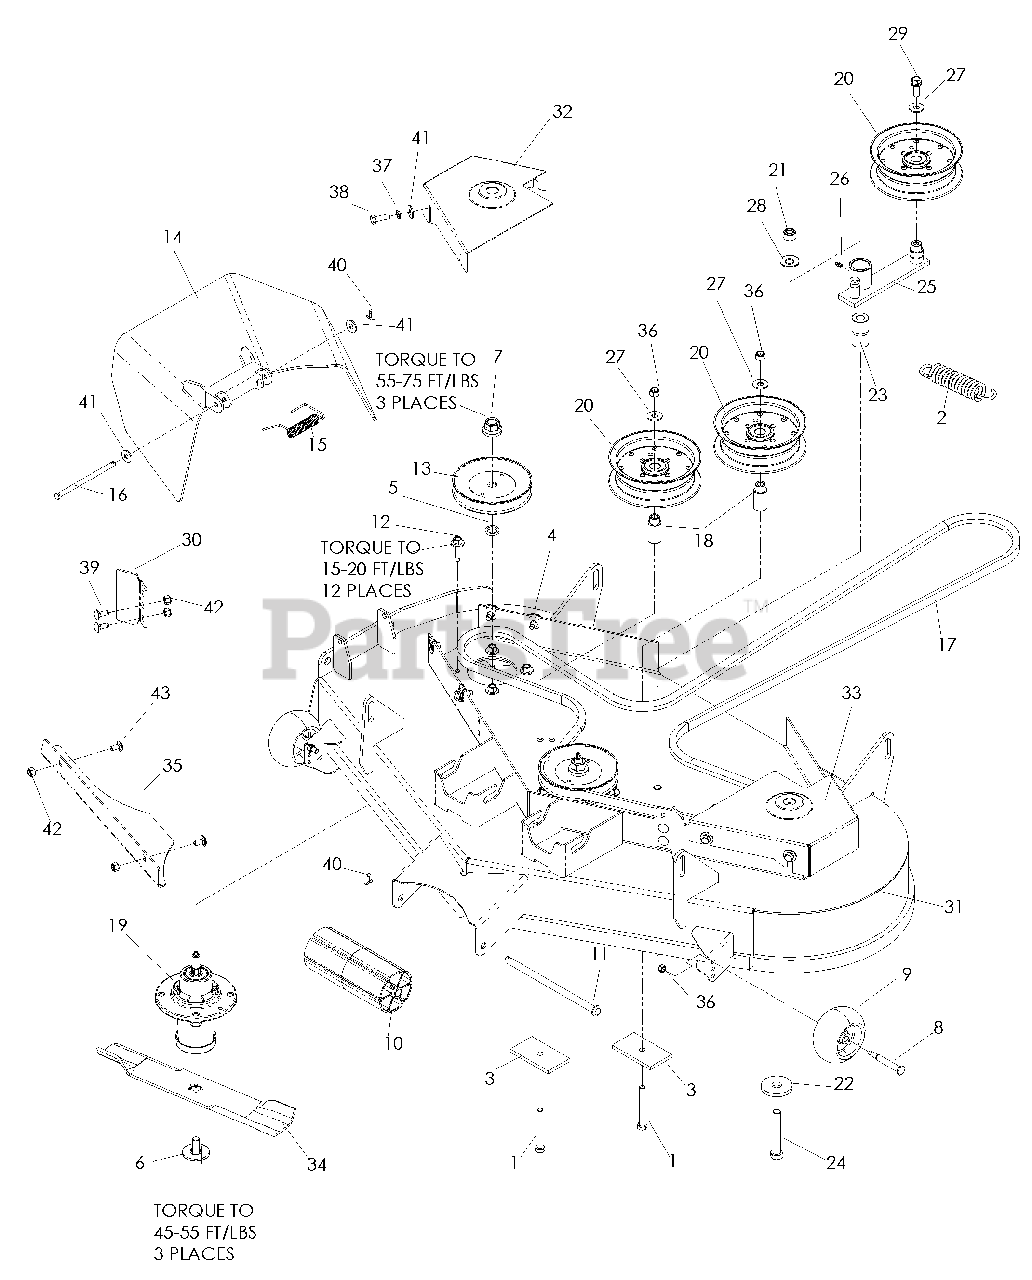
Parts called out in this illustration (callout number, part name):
1	HCS 3/8-16
2	SPRING, EXTENSION
3	PAD
4	NUT 5/16-18 RETAINER-U
5	WASHER .675
6	BOLT 7/16
7	NUT 9/16 TOP CNTLCK
8	BOLT, SHOULDER
9	WHEEL, GAUGE
10	ROLLER, NOSE
11	ROD, ROLLER, NARROW
12	SCREW 5/16-18 x 13/8 WSH HD
13	PULLEY, MANDREL
14	DISCHARGE CHUTE
15	SPRING, TORSION
16	PIN, CLEVIS 5/16 DIA x 5.19
17	DECK BELT
18	IDLER BUSHING
19	HOUSING ASSEMBLY
20	IDLER PULLEY
21	NUT 1/2-13 NYLOC
22	WASHER .65
23	BUSHING, PIVOT
24	HCS 1/2-13 x 3 1/4
26	ZERK, STRAIGHT 1/4-28
27	WASHER 3/8
28	WASHER 9/16
29	HCS 3/8-16 x 1 WHIZLK
31	DECK 48" W/DECALS
32	BELT SHIELD W/DECAL, RT
33	BELT SHIELD W/DECAL, LT
34	BLADE 16 1/4"
35	CONFINEMENT PLATE
36	NUT 3/8-16 NYLOC
37	WASHER 5/16
38	HCS 5/16-18 x 1
39	RHSNB 5/16-18 x 3/4
40	PIN, COTTER 1/8 x 3/4
41	WASHER 5/16
42	NUT 5/16-18 NYLOC
43	RHSNB 5/16-18 x 5/8
